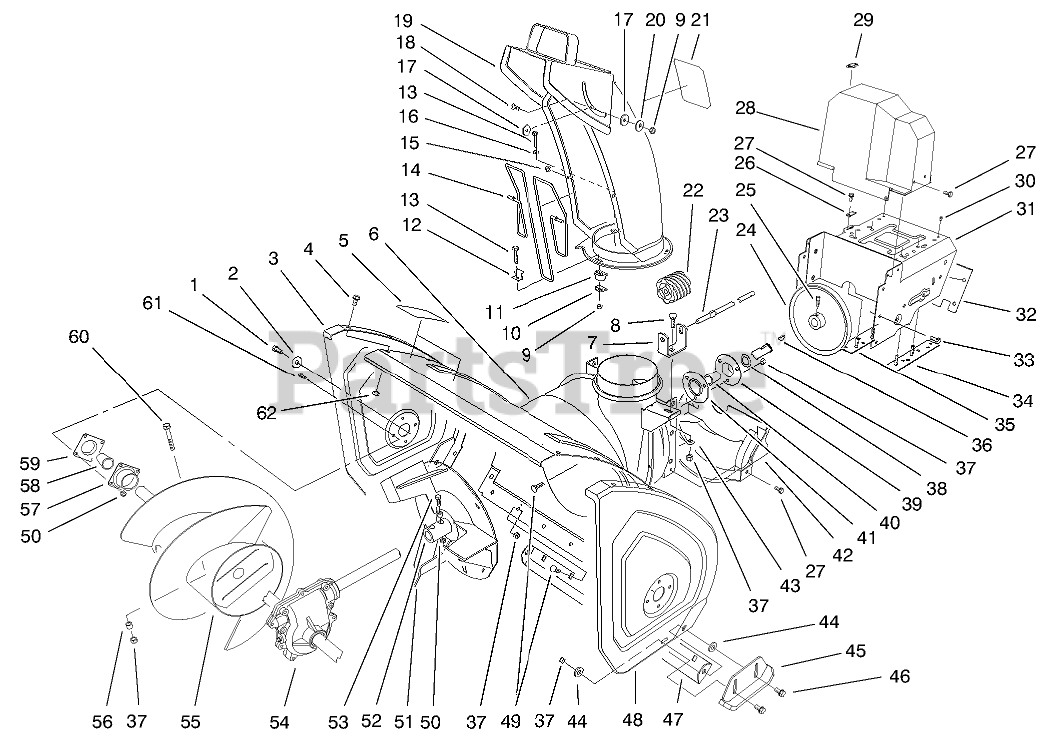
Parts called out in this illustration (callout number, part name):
1	SCREW-HH
2	WASHER
3	PLATE-SIDE, RH
4	SCREW-HHF
6	AUGER HOUSING ASM
6:2	DECAL-WARNING, AUGER (only on: 38053)
7	BRACKET-WORM, CHUTE
8	BOLT-CARR
9	NUT-LOCK, NI
10	PLATE-RETAINER, CHUTE
11	RETAINER-CHUTE
12	CLIP-GUARD, CHUTE
13	SCREW-HSH
14	GUARD-CHUTE
15	NUT-PUSH
16	WASHER-FLAT
17	WASHER-PLASTIC
19	CHUTE
19:2	DECAL-DANGER (only on: 38053)
20	WASHER-FLAT
22	GEAR-WORM
23	ROD-CHUTE, LOWER
24	PULLEY-IMPELLER
25	SCREW-SET, SQH
26	RETAINER-CABLE
27	SCREW-HWH
28	COVER-BELT, UPPER
29	COVER-CABLE
30	RIVET-POP
31	ENGINE FRAME ASM
31:2	DECAL-ADJUSTMENT
32	COVER-FRAME, ENGINE
33	SCREW-HWHTF
34	LH FRAME PLATE ASM
35	RH FRAME PLATE ASM
36	KEY-WOODRUFF
37	NUT-LOCK, NI
38	WASHER-THRUST
39	FLANGE-CUP, BEARING
40	BEARING-BALL
41	FLANGE-CUP, BEARING
42	COVER-BELT, LOWER
43	WASHER-PLAIN
44	WASHER
45	SKID ASM
46	SCREW-HHF
47	SCRAPER BLADE ASM
48	PLATE-SIDE, LH
49	SCREW-CARR
50	NUT-LOCK, NI
51	BLADE IMPELLER ASM
52	SPACER
53	SCREW-HHF
54	AUGER GEARCASE ASM
55	RH AUGER ASM
56	SPACER-HUB, AUGER
57	BEARING-FLANGE, FRONT
58	BEARING
59	BEARING-FLANGE, REAR
60	SCREW-HH
61	SCREW-HH
62	NUT-LOCK, NI
